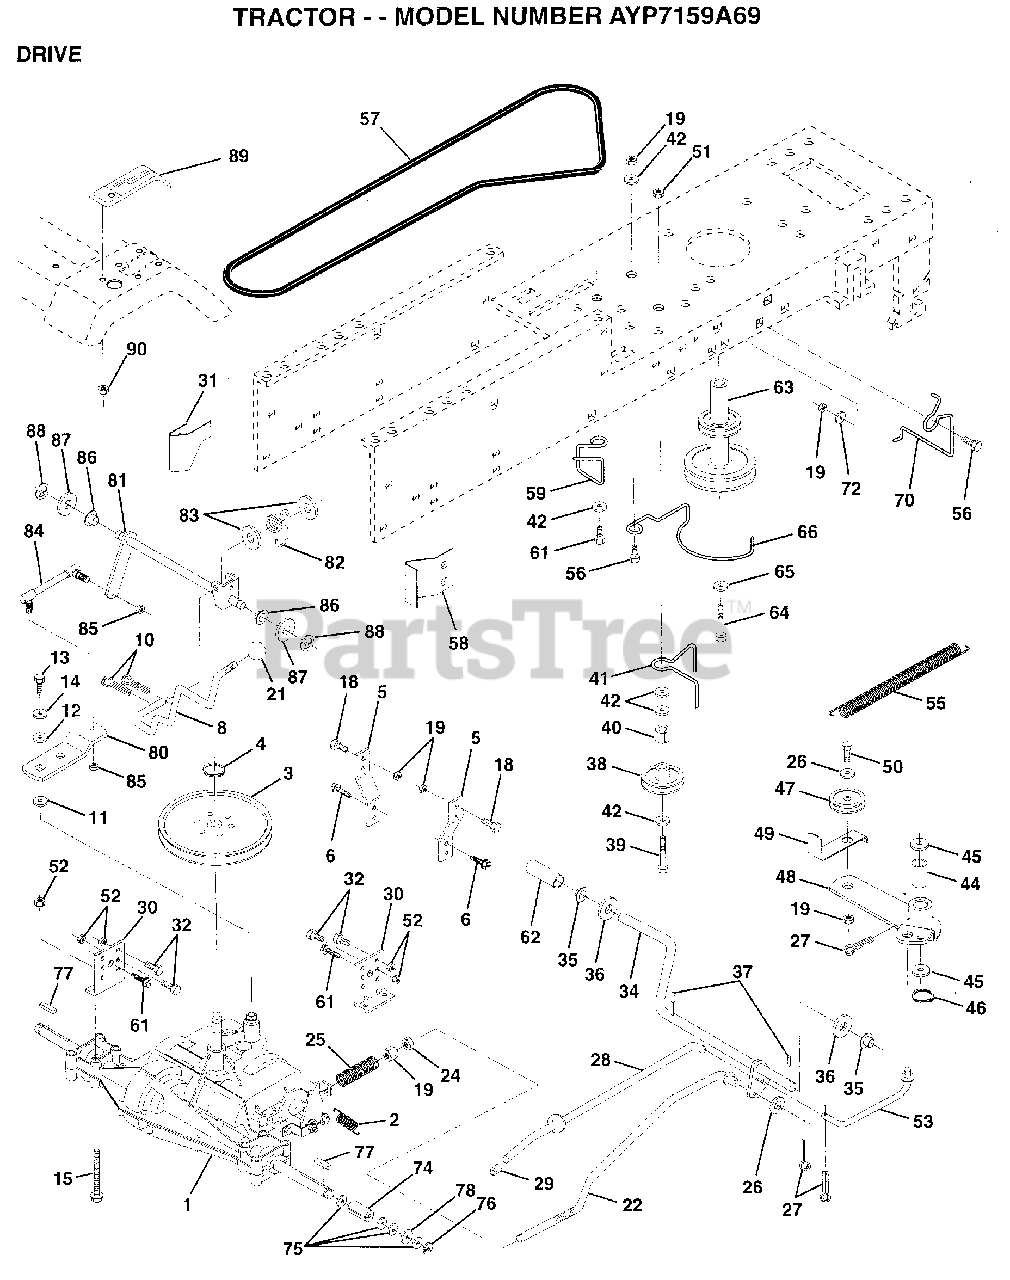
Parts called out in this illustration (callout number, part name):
2	SPRING.BRAKE.RETU
3	PULLEY TRANS
5	SPRING
6	SCREW
8	ROD SHIFT FEND LT
10	PIN COTTER 1/8
11	WASH-SHFT PLT LT
12	WASHER
13	BOLT.1/4-28.W/PAT
14	LOCKWASHER
15	BOLT.HX.FLG.5/16
18	BOLT
19	NUT
21	KNOB T (1/2-HOLE)
22	BRAKE ROD
24	NUT
25	SPRING ROD LT
26	WASHER
27	COTTER PIN
28	ROD.BRAKE.PARK.LT
30	TRANSAXLE MTG BKT
31	"KEEPER,BELT LH T"
32	BOLT
34	SHAFT.PEDAL.FOOT
35	NYLON BEARING
36	WASHER LT
38	PULLEY.IDLER.FLAT
39	BOLT
40	SPACER T
41	BELT KEEPER LT
42	WASHER
44	"LY, BEARING"
45	WASHER LT
46	KLIP RING
48	ARM IDLER
49	RETAIN BELT
52	NUT
53	"LINK, CLUTCH T"
55	"SPRING, RETURN LT"
56	BOLT RDHD 3/8-16
58	"KEEPER,BELT RH T"
59	KEEPER BELT CNTSP
61	SCREW
62	PEDAL COVER T
63	PULLEY.ENGINE
64	BOLT
65	LOCKWASHER
66	KEEPER.BELT.ENG.L
70	KEEPER BELT ENG
72	WASHER
74	SPACER LT
75	WASHER
76	E-RING LT
77	SQUARE KEY
78	WASHER
80	ARM SHIFT TRANS
81	SHAFT ASM.SHIFT
82	"SPRING,TORSION"
83	WASHER
84	TIE ROD
85	NUT.CNT.LOCK.1/4
86	BUSHING
87	WASHER D
88	KLIP RING
90	NUT
